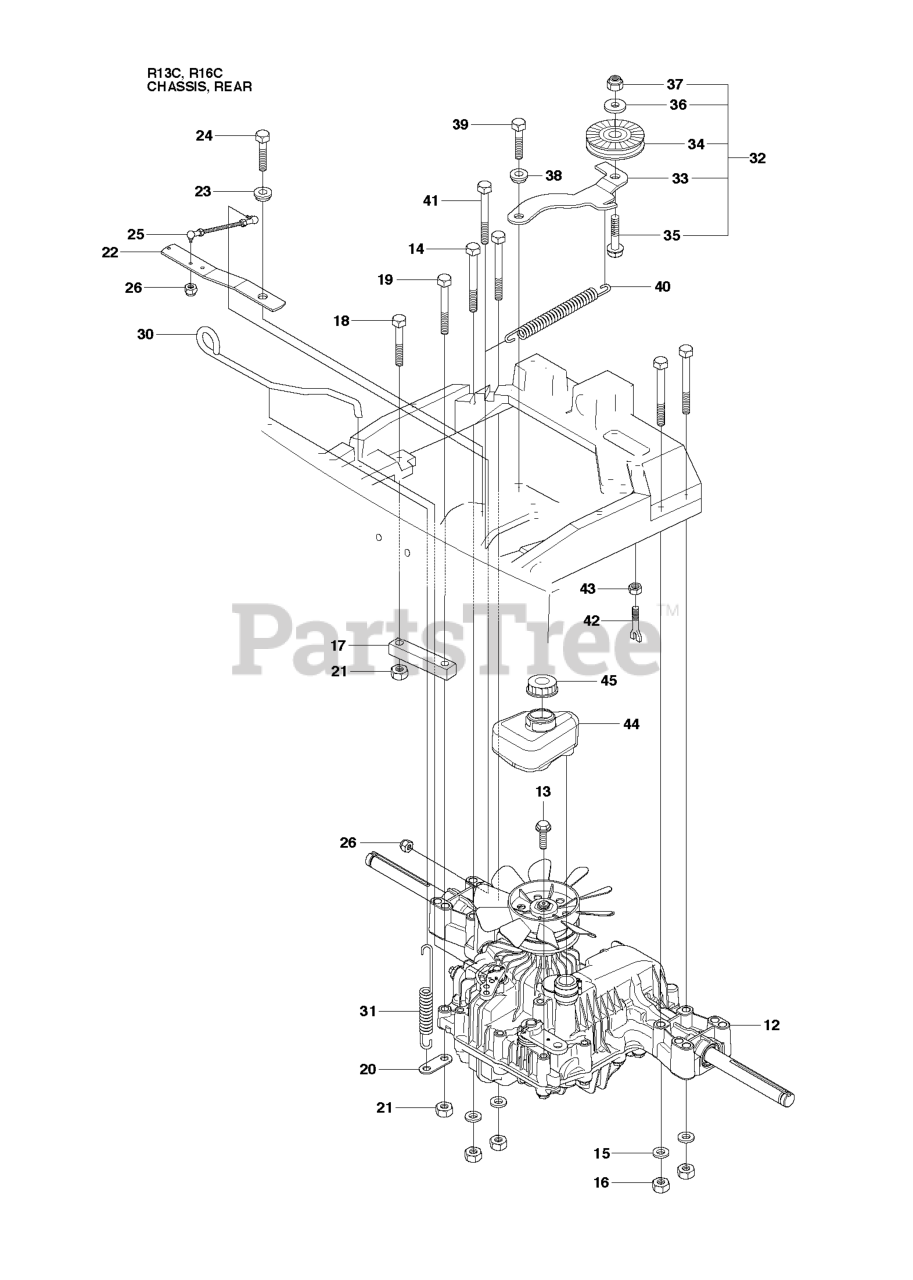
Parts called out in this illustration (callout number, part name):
12	HYDROSTAT 7A646024070
15	WASHER BRB 8.4X17
16	NUT
21	NUT
23	WASHER
24	SCREW 8X20
26	LOCKNUT M5
33	TENSIONER
35	SCREW
37	LOCKNUT M8
38	WASHER
39	SCREW 8X20
43	NUT
45	TANK CAP
